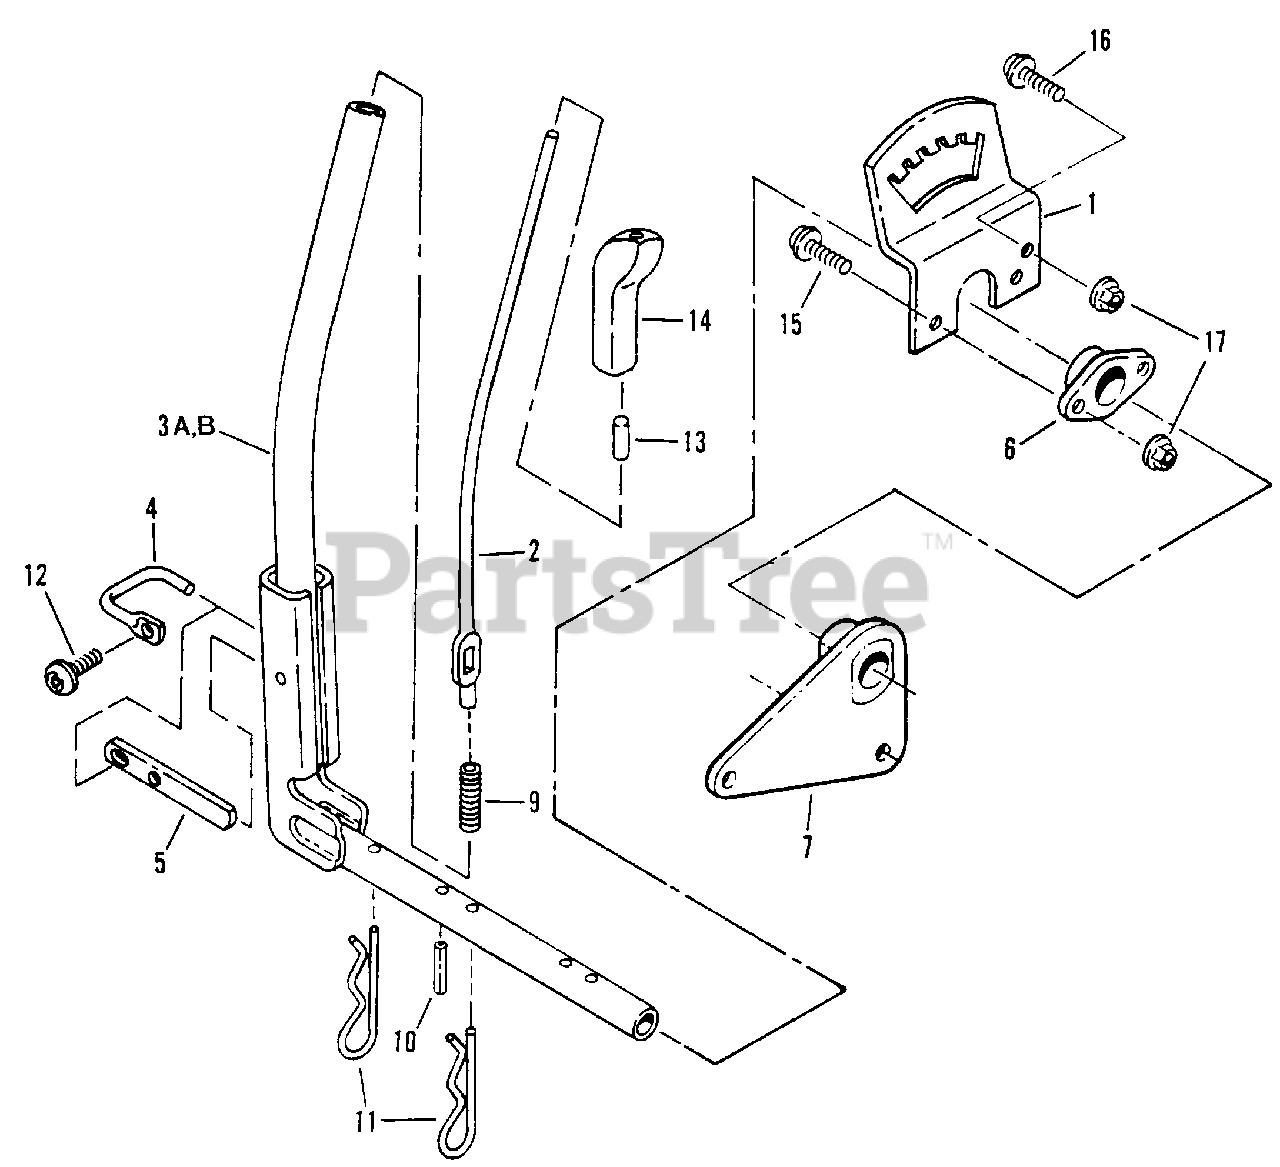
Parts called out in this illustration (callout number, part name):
1	QUADRANT, Lift Lever
2	ROD, Lift Lever
3A	STRUCTURE, Lift Lever
3B	STRUCTURE, Lift Lever
4	LATCH, Pivot
5	DETENT, Latch
6	PIVOT, Lift Lever
7	BELL-CRANK, Lift Structure
10	PIN, 1/4" x 1-1/8" Dowel
11	PIN, 5/32" x 2-5/8" Hair
12	SCREW, 1/4-20 X 5/8" Truss Head Torx
13	CAP, Lever Rod
14	KNOB, Lift Lever
15	SCREW, 5/16-18 x 7/8" Truss Head Torx
16	SCREW, 5/16-18 x 5/8" Truss Head Torx
17	NUT, 5/16-18 Hex Flange Lock
